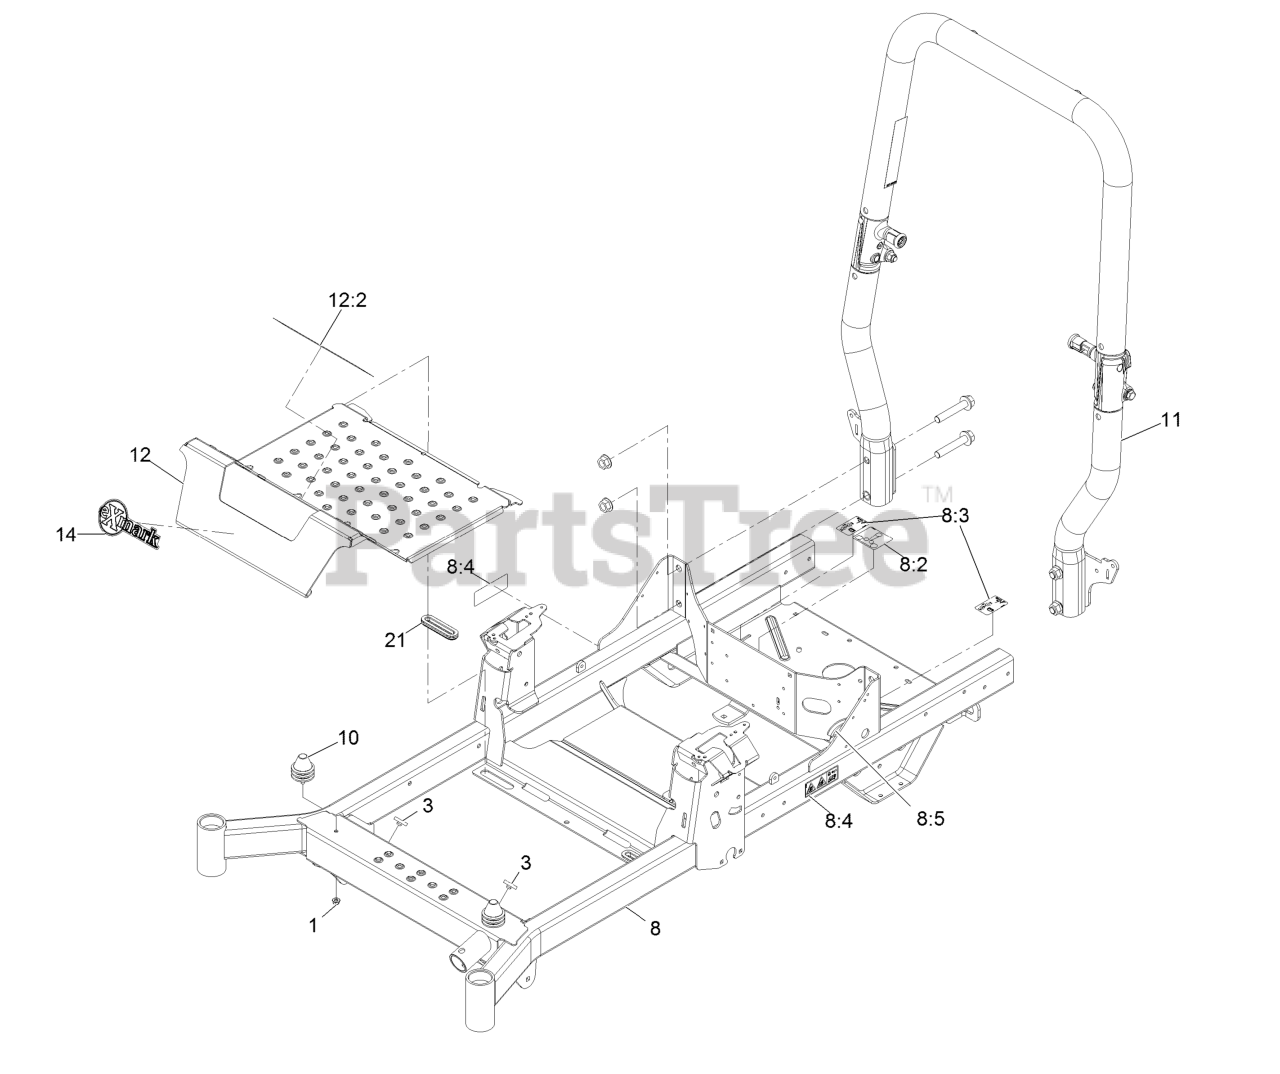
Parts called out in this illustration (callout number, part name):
1	Nut-Nyloc 5/16-18 Flg
3	Bumper-Push-In, Rubber
8	Frame ASM
8:2	Decal-Routing, Belt
8:3	Decal-Release, Drive
8:4	Decal-Warning
8:5	Strip-Seal
10	Isolator
11	ASM-ROPS Tapered
12	Pan-Floor
12:2	Decal-Danger
14	Decal-Exmark Logo
21	Grommet-Rubber
